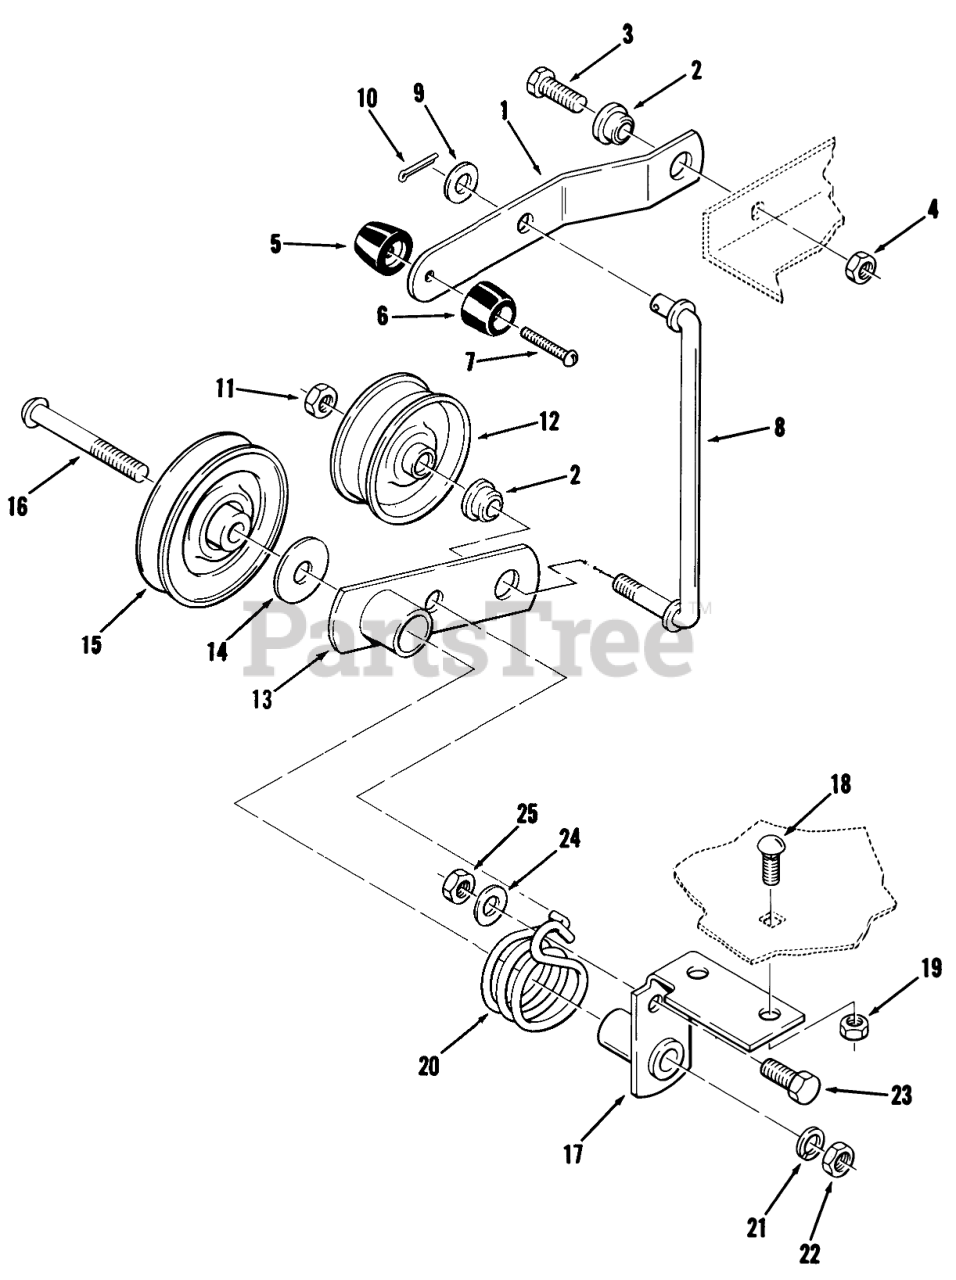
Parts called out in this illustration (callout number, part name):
1	LEVER-DR CLUTCHING
2	SPACER-BRAKE LINK
3	BOLT
4	Nut
5	KNOB
6	KNOB
7	BOLT-4
9	Washer
10	Pop Rivet
11	Nut
12	IDLER PULLEY
13	ASSY-IDLER ARM
14	WASHER
15	PULLEY-IDLER
16	SCREW 3/8-16X23/4
17	Idler Arm Support
18	Bolt
19	Nut
20	SPRING-TORSION
21	LOCKWASHER
22	Nut
23	Bolt
24	Washer
25	Nut
